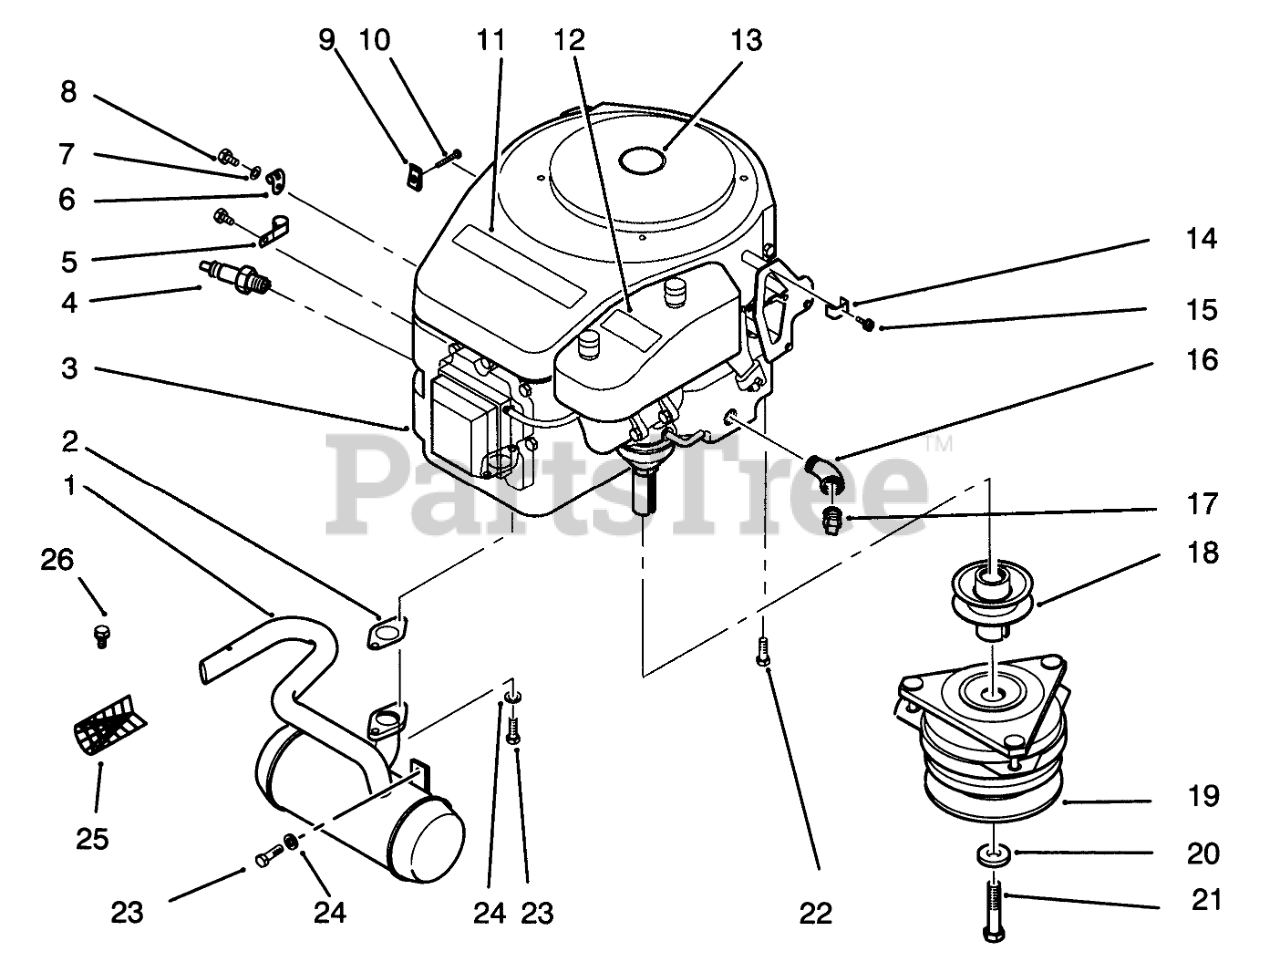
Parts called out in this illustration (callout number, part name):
1	MUFFLER
2	GASKET-EXHAUST
3	ENGINE-E14OV
4	SPARK PLUG
5	J-CLIP
6	CLEVIS
7	Washer
8	Screw
9	J-CLIP
10	HHCS M8X1.25X15
11	DECAL-PWR PLUS
12	DECAL-14.0 POWER PLV
13	DECAL-TORO ENGINE
14	CLAMP-CONTROL
15	Bolt
16	STREET ELBOW 45DEGRE
17	Plug
18	PULLEY-ENGINE HYD R
19	Clutch
20	WASHER
21	HHCS-M10X1.5X110 ESL
22	Bolt
23	HHCS M8X1.25X20
24	WASHER-LOCK
25	Arrester-Spark
26	BOLT-HEX S.T. #8X1/2
